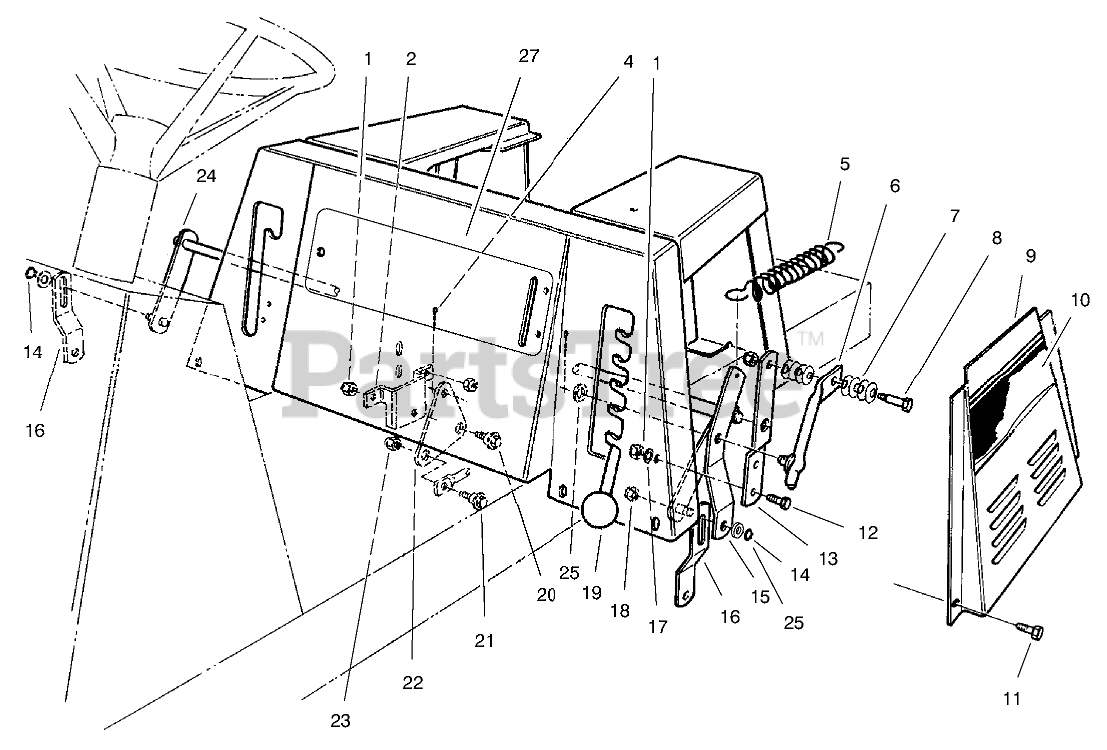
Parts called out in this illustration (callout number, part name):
1	NUT-LOCK, NI
2	BRKT-B.CRANK MTG
4	PIN-COTTER
5	SPRING-EXTENSION
6	HOC LEVER WA B
7	WASHER-BELLEVILLE
8	BOLT-SHOULDER
9	Panel L.H.-Base, Seat
10	DECAL - SIDE
11	SCREW-HH
12	SCREW-HH
13	Bracket
14	RING-RETAINING
15	Bracket-H.O.C., Engage
16	Link-Deck Suspension
17	WASHER-PLAIN
18	NUT-LOCK, NI
20	SCREW-SHOULDER
21	SCREW-SHOULDER
22	BELLCRANK
23	NUT-HEX
24	Arm
25	WASHER-FLAT
27	DECAL - CONTROL PANEL
